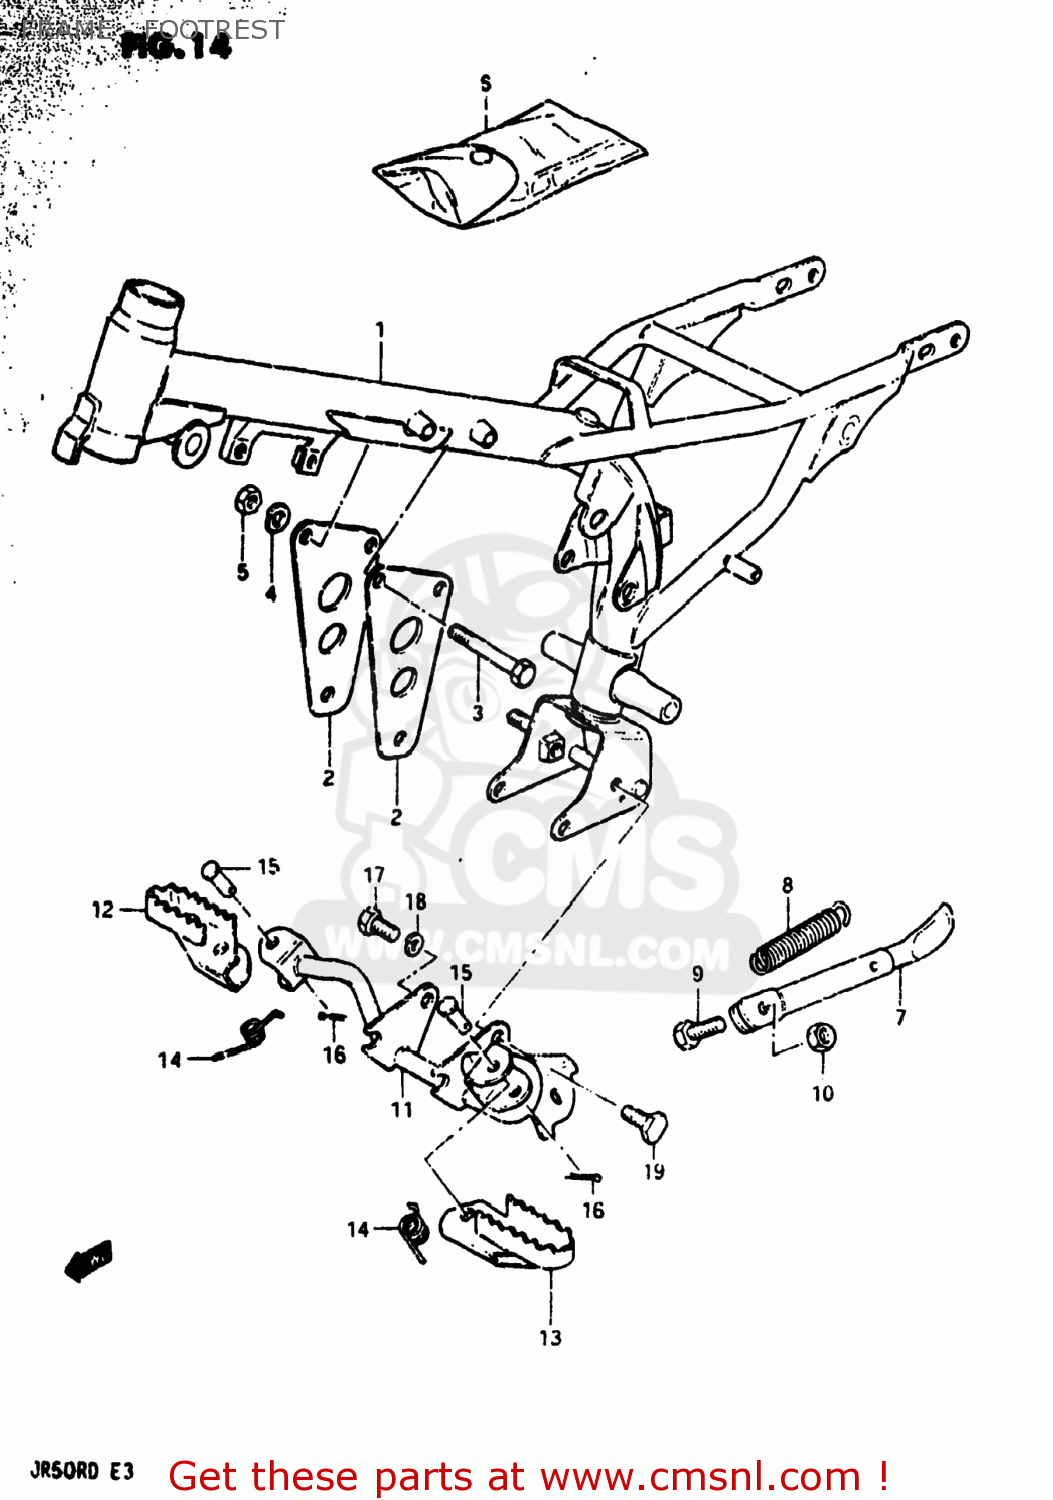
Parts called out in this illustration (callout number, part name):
1	FRAME (BLACK)
2	PLATE,ENG MTG
3	BOLT
4	LOCK WASHER
5	NUT
6	TOOL SET
7	STAND,PROP
8	SPRING
9	BOLT 8X22
10	NUT
11	BAR,FR FOOTREST
12	FOOTREST,FRONT,RIGHT
13	FOOTREST
14	SPRING
15	PIN
16	PIN 20X20
17	BOLT
18	LOCK WASHER
19	BOLT(8X14)
